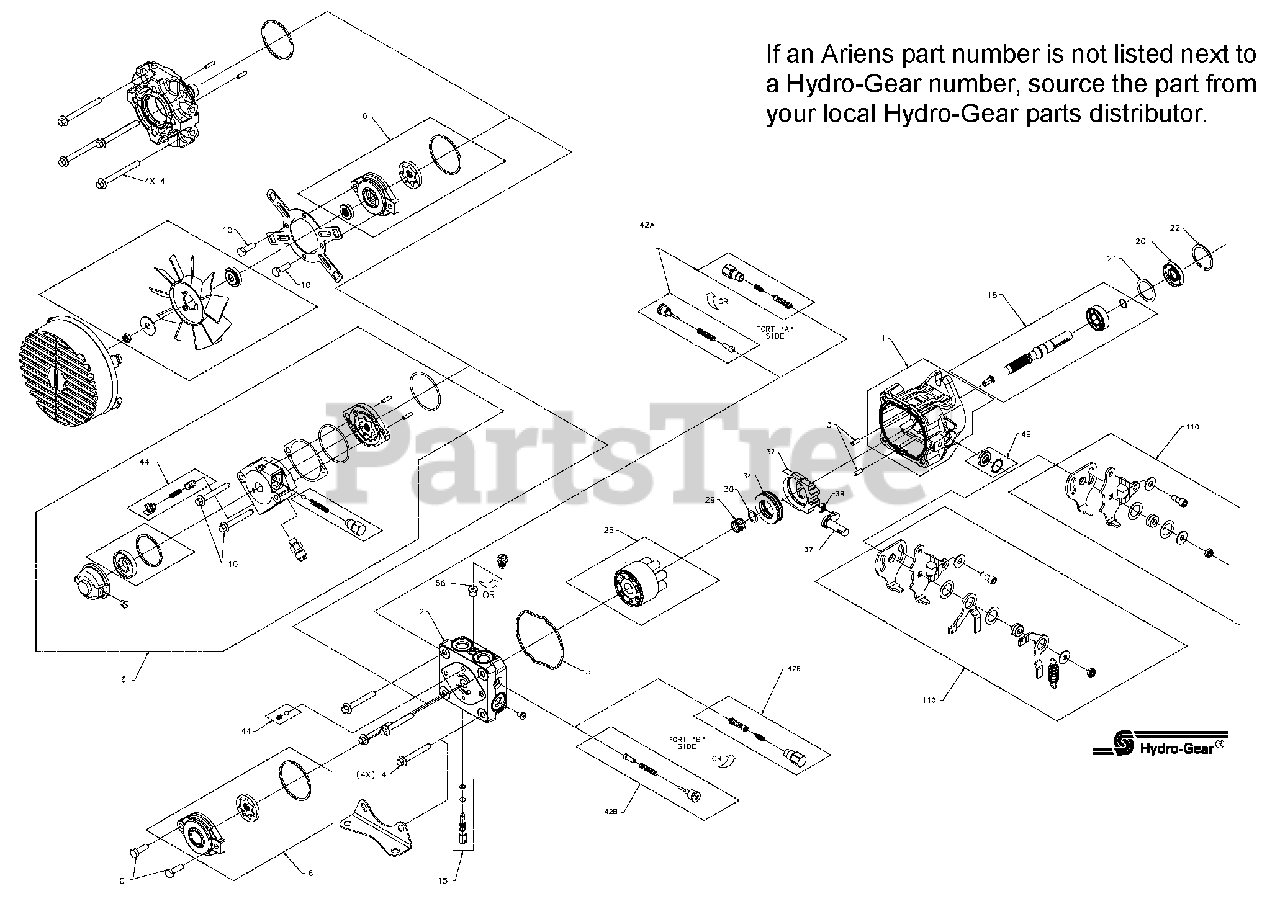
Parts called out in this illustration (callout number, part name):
1	Kit, Housing
2	End Cap
3	Straight Headless Pin
4	Hex, Flange Bolt M8-1.25 x 60mm
5	Housing O-Ring
6	Kit, Charge Pump
10	Screw 5/16-18 x 1.00
15	Bypass Valve Kit
18	Kit, Pump Shaft (15mm Straight Keyed Thru)
20	Lip Seal 17 x 40 x 7 PTC
21	Spacer
22	Retaining Ring
29	Block Spring
30	Block Thrust Washer
32	Swashplate
34	Ball Thrust Bearing
37	Arm, Trunnion, Tapered Square
38	Slot Guide
42	Kit, Shock Valve (200 Bar .031 Orifice)
44	Charge Relief Kit
49	Trunnion Seal - Retainer Kit
56	Plug, 7/16-18 Steel
110	Kit, CW Rtn Scissor
NS	Auxiliary Filter Kit
NS	Overhaul Seal Kit
